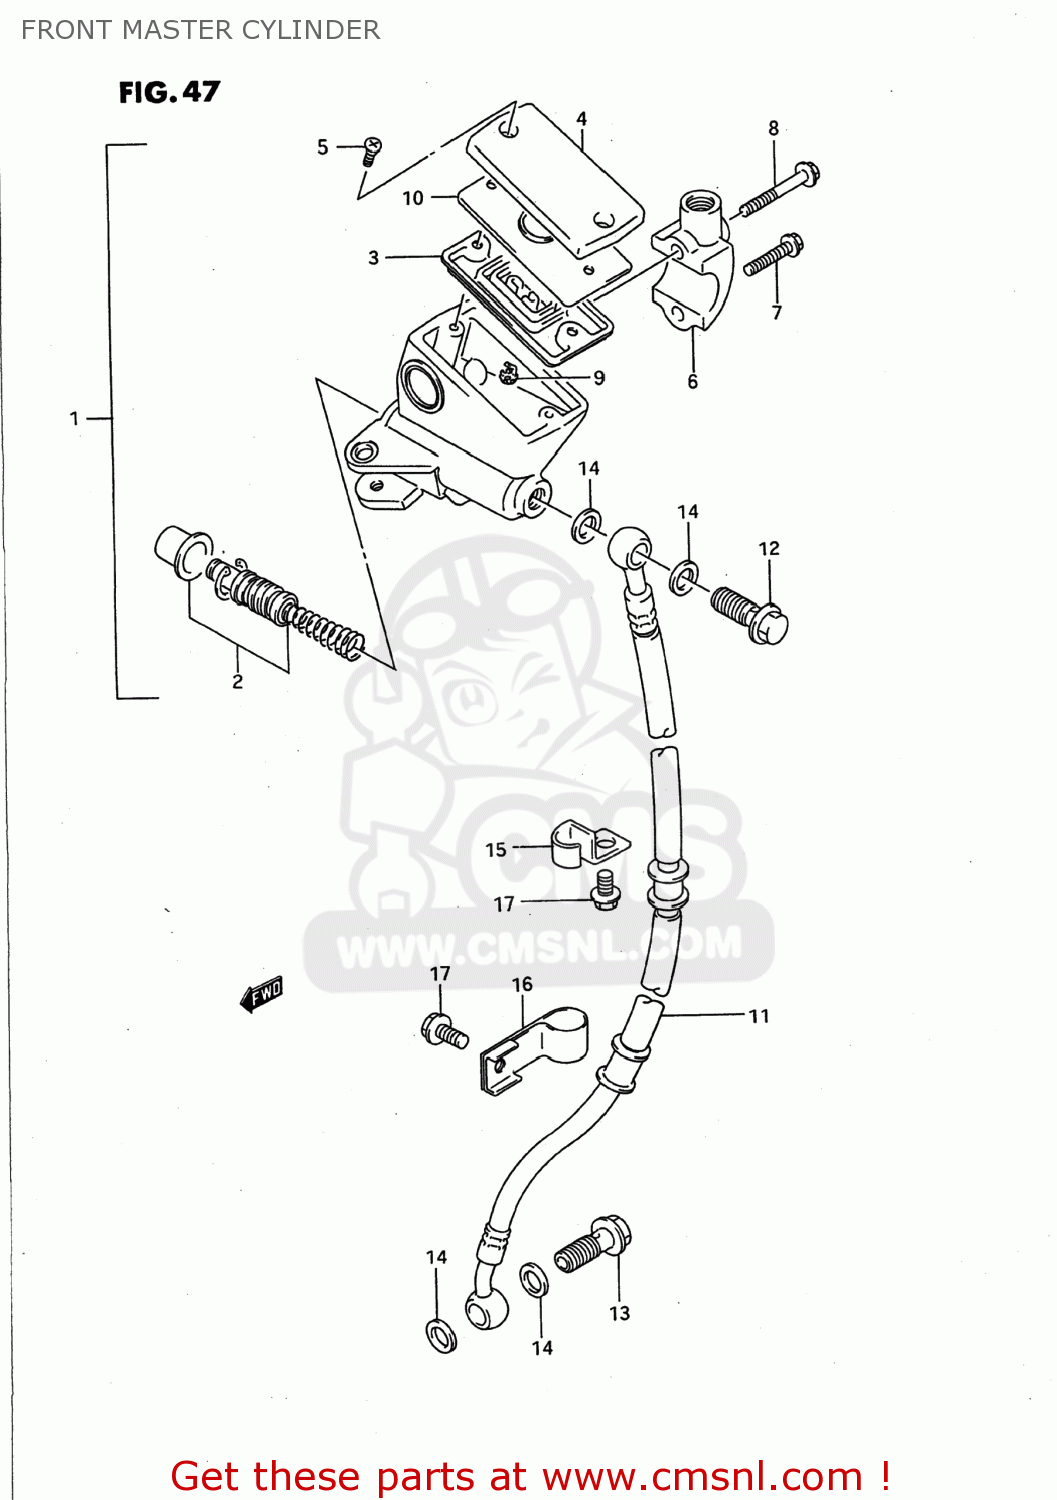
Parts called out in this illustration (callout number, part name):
1	CYLINDER ASSY,FR MASTER
2	CUP SET,MASTER CYLINDER
3	4-1
4	CAP
5	SCREW
6	HOLDER
7	BOLT(6X25)
8	BOLT(6X38)
9	PROTECTOR
10	PLATE,DIAPHRAGM
11	HOSE,FR BRAKE,R
12	BOLT UNION
13	BOLT UNION
14	WASHER(10X15X1.5)
15	CLAMP,FR BRAKE HOSE
16	CLAMP,FRONT BRAKE NO.2
17	BOLT
